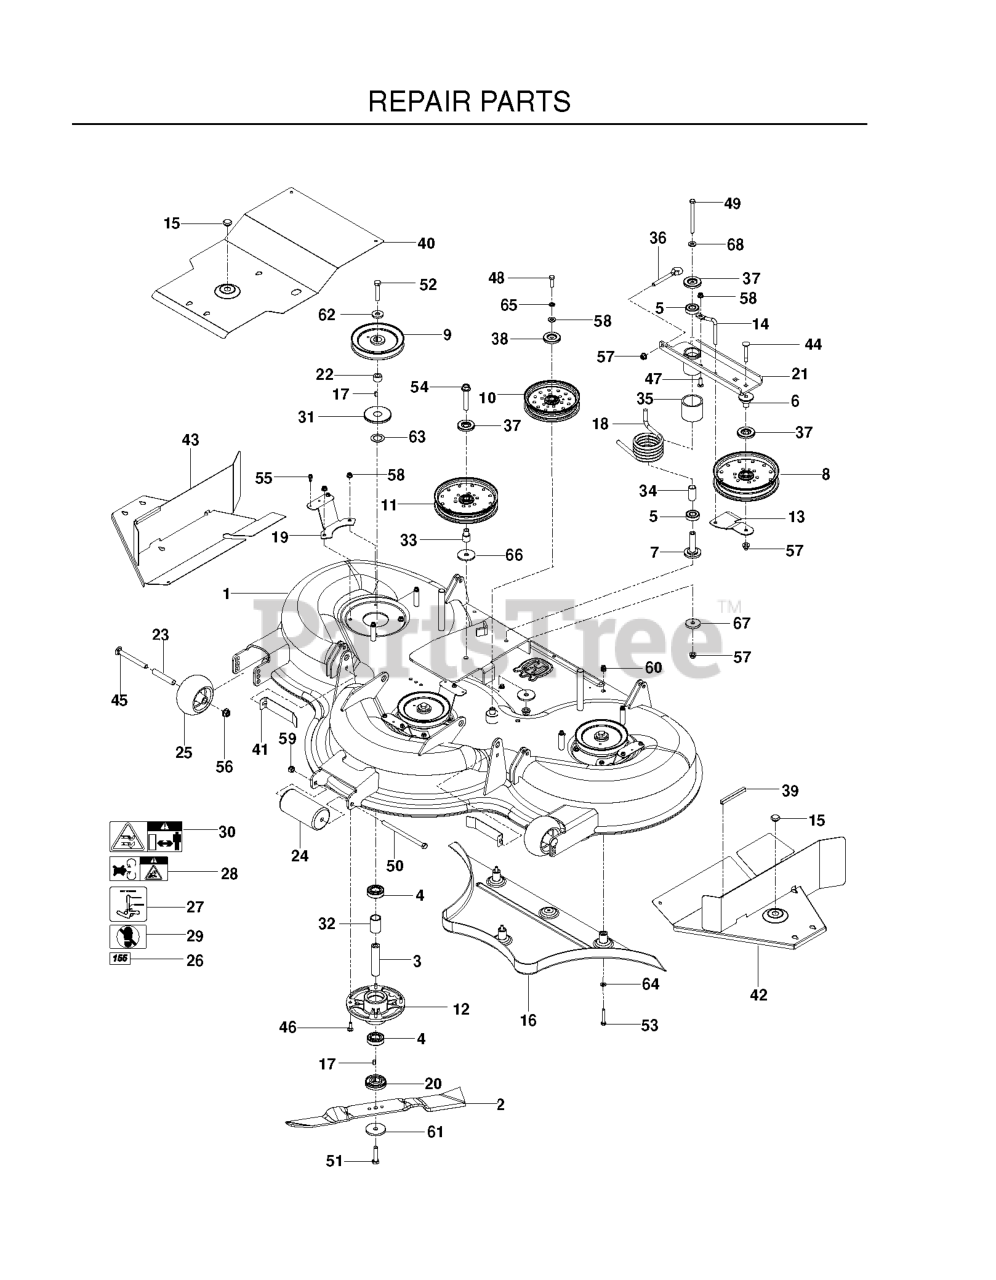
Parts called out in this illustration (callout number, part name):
1	DECK W/SAFETY DECALS
4	BALL BEARING
5	BEARING, BALL
6	BEARING, IDLER ARM
7	BEARING, IDLER PIVOT
8	PULLEY - IDLER 7"
9	PULLEY, 61
10	PULLEY IDLER, 6" NARROW
11	PULLEY - 7" NARROW
12	BEARING HOUSING
13	BELT.GUIDE.BLACK
14	BELT KEEPER
15	PLUG, BUTTON HOLE
16	PLUG ASSEMBLY
18	SPRING, TORSION, IDLER
19	BRACKET,BELT CVR,COMBI BLK
20	BUSHING, BLADE
21	IDLER.ARM.BLACK
22	KEY RETAINER
23	TUBE, ROLLER AXLE
24	ROLLER
25	ROLLER, GAUGE .635 BORN
26	DECAL, 155
27	DECAL, BELT ROUTING
28	DECAL, BELT DRIVE
29	DECAL, NO STEP
30	DECAL, EURO SEVERING
31	TOP DUST CAP
33	SPACER - IDLER
34	SPACER, IDLER BEARINGS
35	SPACER, IDLER PIVOT
36	EYE BOLT, 3/8 X 4"
37	DUST SHIELD
38	SHIELD, DUST
39	RP.FLEX TRIM, BLK-LENGTH 1 FT
40	GUARD.CENTER.COMBI.61.BLACK
41	GUARD, COMBI STRUT, BLK
42	WLDMNT, LEFT COMBI 61, BLK
43	WLDMNT, RIGHT COMBI 61, BLK
44	CARRIAGE BOLT 3/8-16 X
45	RHSNB 1/2-13 X 4.75 GR5 ZD
46	RHSNB 5/16C X 1
47	RHSSNB 5/16C X 1.0
48	HCS 3/8C X 1 1/4 GR5
49	HCS 3/8F X SPECIAL
50	HCS 7/16-14 X 7 GR5 ZD
51	HCS M12 X 1.75 X 50 GR8.8 ZD
52	HCS M12 X 1.75 X 60 GR5 ZD
53	HCS M8 X 1.25 X 50 GR8.8 ZD
54	HFFS 1/2-13 X 3 GD 5 ZD
55	SCREW- 1/4-20 X 5/8
56	NUT, 1/2-13 HEX FLG NYLOC ZD
57	NUT 3/8-16 HEX FLG NYLOC ZD
58	5/16-18 NYLOC FLANGE NUT
59	NUT 7/16C CENTERLOCK
60	BLIND RIVET NUT
62	WASHER-.533IDX1.37OD
63	WASHER-1.06IDX1.63ODX.06
64	FLAT WASHER 5/16 SAE
65	SLW 3/8 STD
66	WASHER, HEAVY
67	SPINDLE WASHER
68	WASHER, 3/8 THICK
